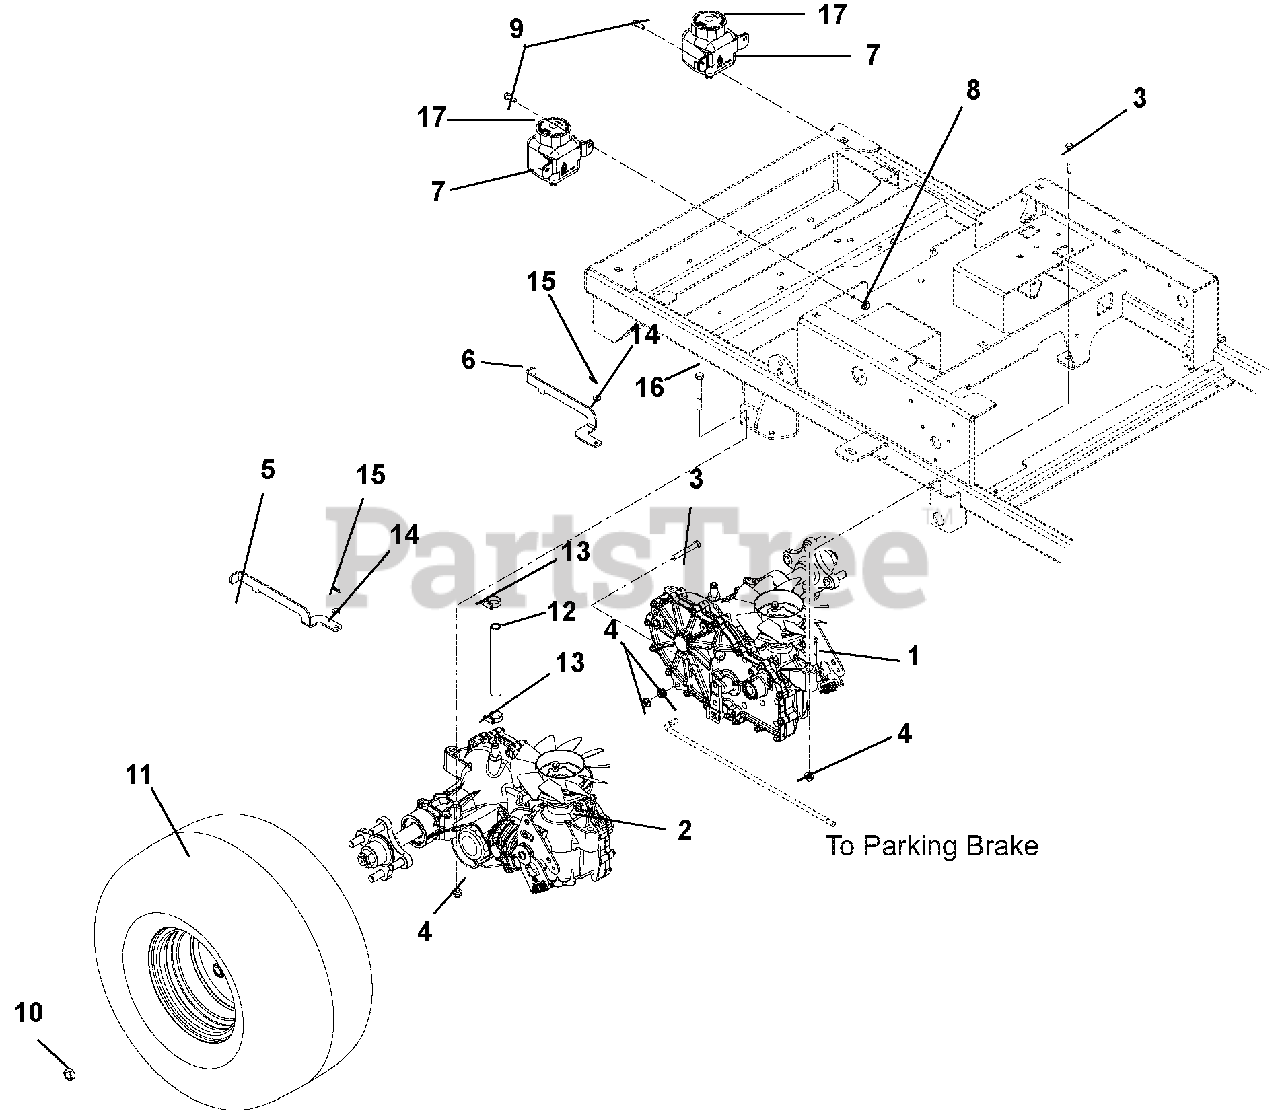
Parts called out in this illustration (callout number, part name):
1	TRANSAXLE, ZT2800 LH
2	TRANSAXLE, ZT2800 RH
3	@BLT-HEX .31-18X2.25 GR5 YWZC
4	@NUT-LK-NYL-FLG .31-18 YWZC
5	DUMP VALVE, RH
6	DUMP VALVE, LH
7	TANK, EXPANSION
8	@NUT-LK-TOP-FLG .25-20 YWZC
9	@BLT-HEX .25-20X.75 GR5 YWZC
10	WHEEL NUT .500-20 YZ
11	TIRE/WHEEL ASSY, 20X10.0-8 CTR
11	TIRE/WHEEL ASM, 20X8.0-8 (SQ)
12	HOSE, OIL RESERVOIR
13	CLAMP,.88 DIA. HOSE
14	WSHR-FL-STL .265X.50X.087YWZC
15	PIN-HAIR INT .06X.18X.77
16	@BLT-HEX .31-18X2.75 GR5 YWZC
17	CAP, HYDRO RESERVOIR REPLAC.
